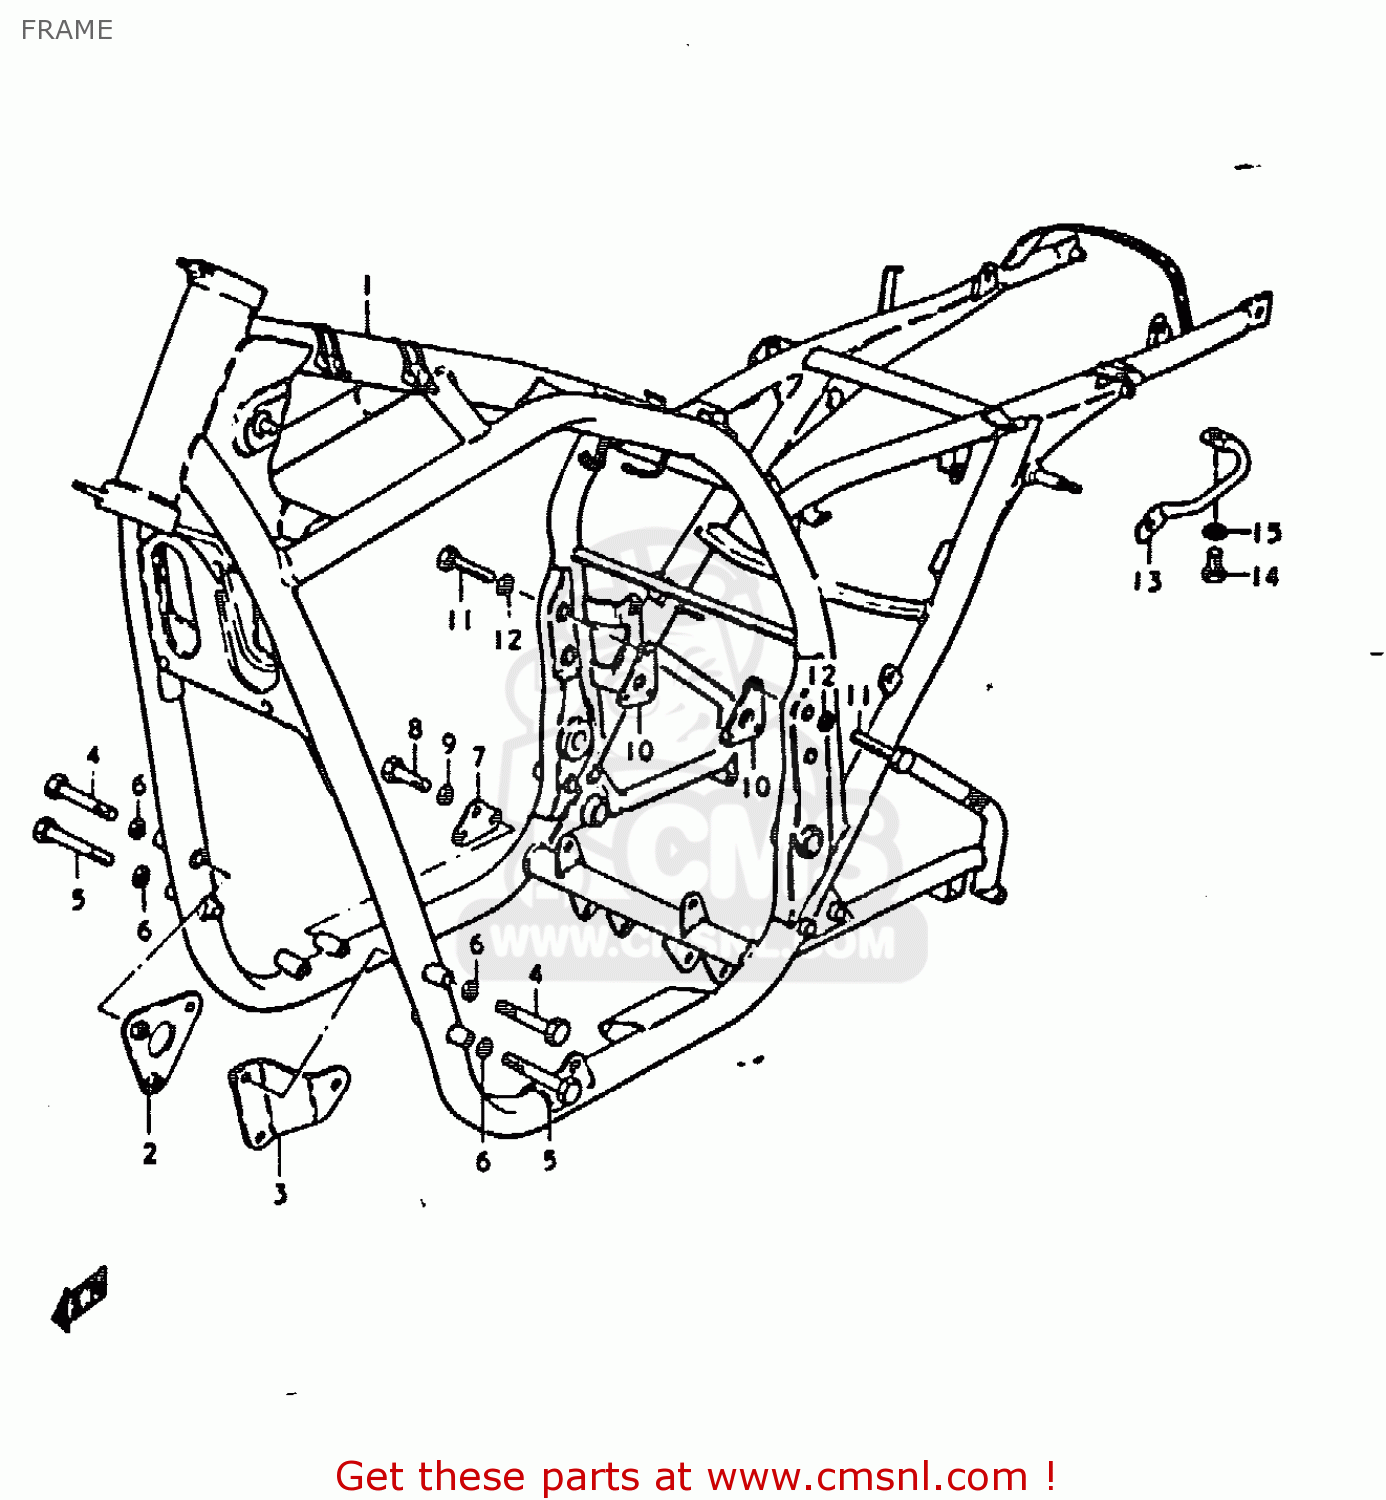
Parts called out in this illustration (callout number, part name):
1	FRAME
2	PLATE,ENGINE MOUNTING
3	PLATE,ENGINE MOUNTING
4	BOLT
5	BOLT
6	LOCK WASHER
7	PLATE,ENGINE MOUNTING
8	BOLT
9	LOCK WASHER
10	PLATE,ENGINE MOUNTING
11	BOLT
12	LOCK WASHER
13	GRIP,FRAME
14	BOLT
15	WASHER
